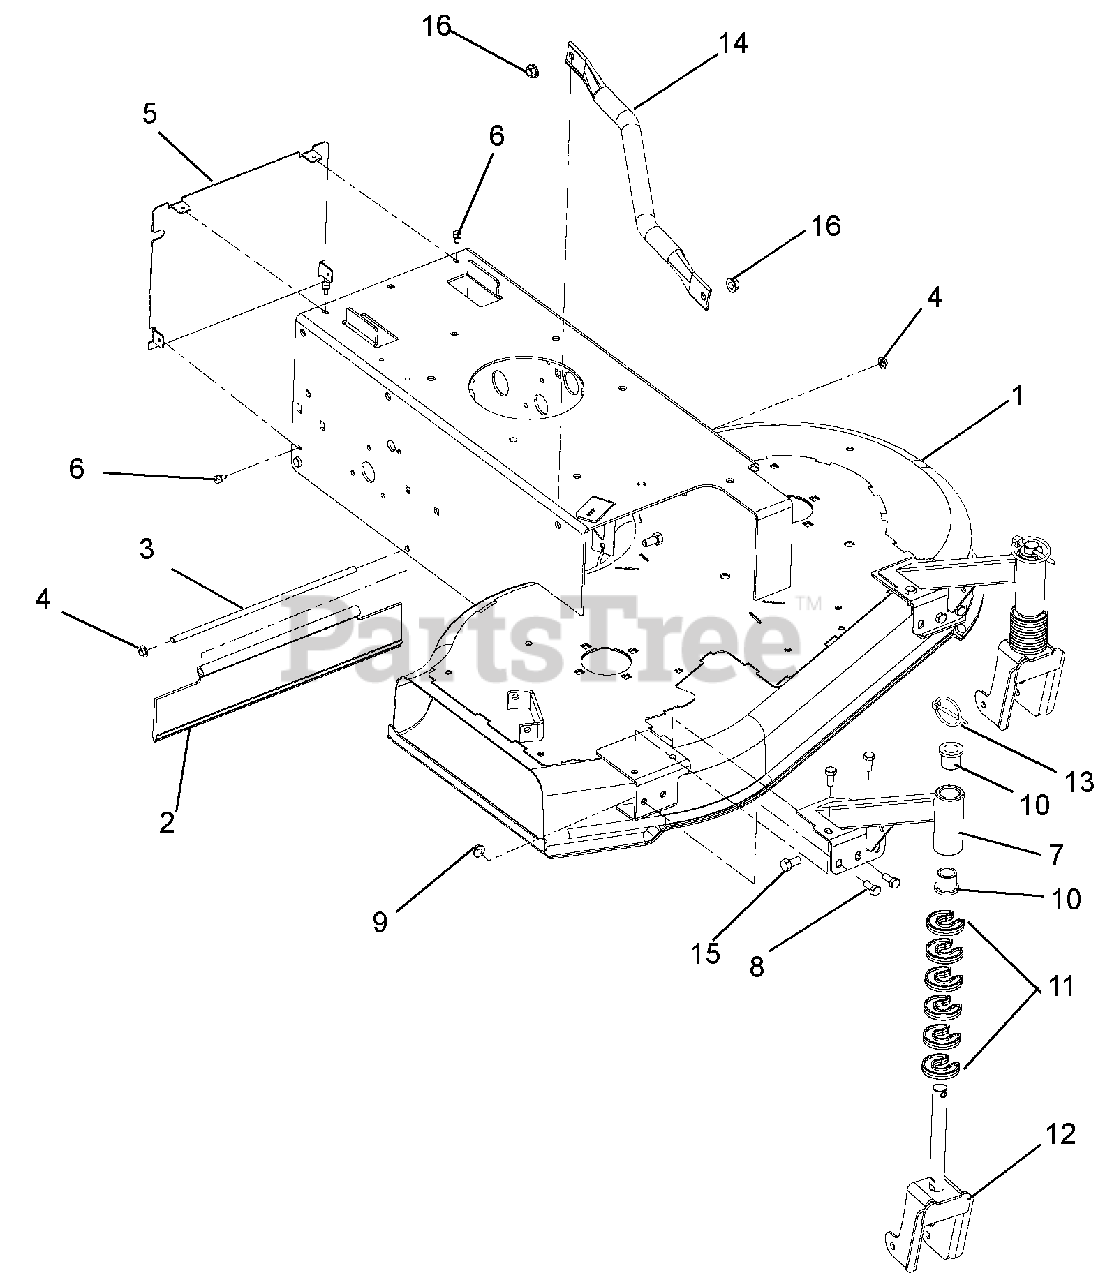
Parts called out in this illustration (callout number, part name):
1	CHASSIS, WAW ARIENS
2	GUARD - REAR - SWIVEL
3	ROD, TRAILING SHIELD
4	NUT-PUSH .312 DIA. PAL
5	COVER-REAR, CHASSIS
6	SCR-TAP 10-24X.375 PRE-COAT 80
7	WMT-ARM, CASTER
8	@BLT-HEX .31-18X.75 GR5 YWZC
9	@NUT-LK-TOP-FLG .31-18 YWZC
10	BUSHING-1"X.75"X1"
11	CLIP-HOC FIXED
12	FORK, WAW CASTER (WLDMNT)
13	PIN, LYNCH - .25 X 1.25
14	TUBE-BRACE, DECK
15	@BLT-HEX .38-16X.75 GR5 YWZC
16	@NUT-LK-TOP-FLG .38-16 YWZC
